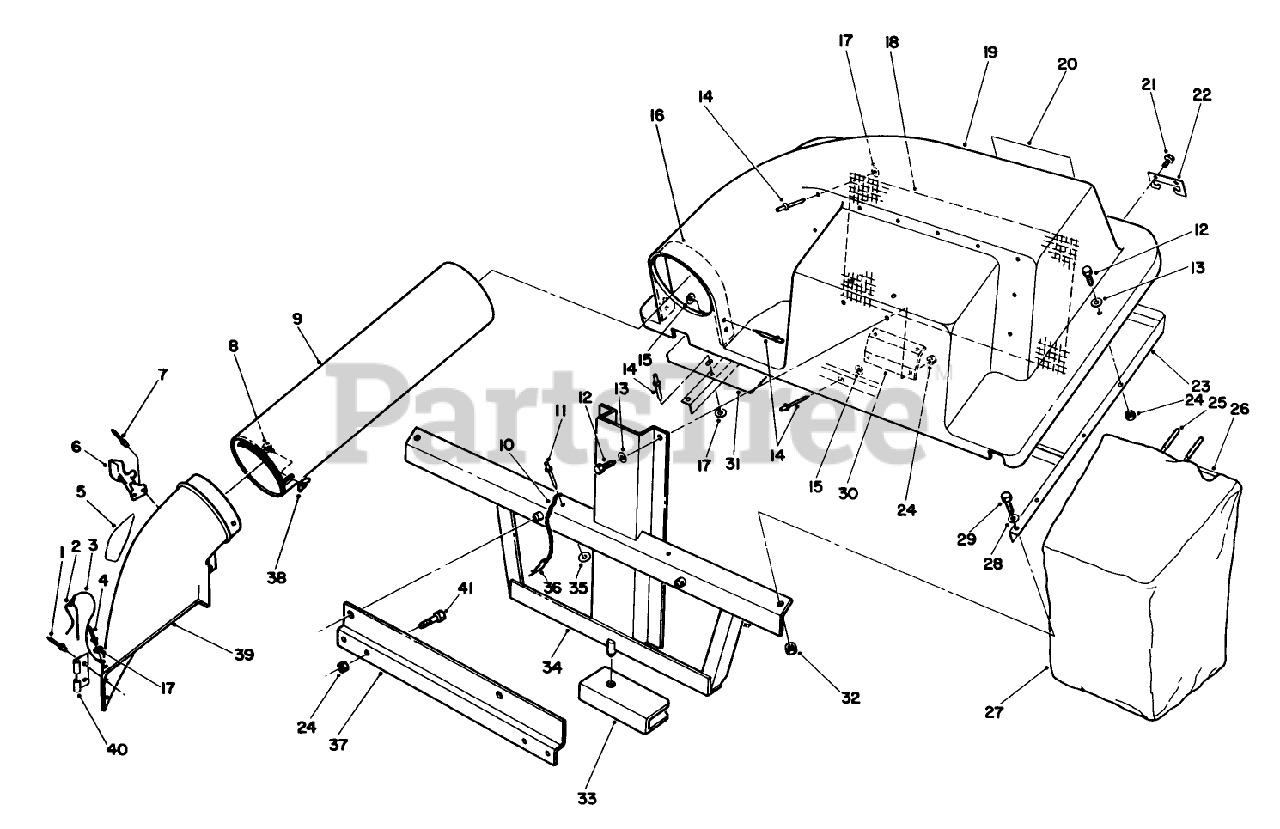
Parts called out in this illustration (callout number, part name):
1	RIVET-BLIND
2	PIN-LOCKING, CHUTE
3	LANYARD
4	RIVET-BLIND
7	RIVET-POP
8	BOLT-CARR
12	SCREW-HH
13	WASHER-PLAIN
14	RIVET-POP
15	WASHER-FLAT
17	WASHER-PLAIN
18	SCREEN
19	COVER-BAGGER, TWIN
20	DECAL-BAGGER, TWIN
21	SCREW-HWH
22	BRACKET-FRAME, BAG
24	NUT-LOCK, NI
25	GRIP-HANDLE, BAG
28	WASHER-FLAT
29	SCREW-HH
32	NUT-LOCK, NI
33	GRASS CATCHER BRKT*
35	WASHER-BACK
36	PIN-HAIR
38	NUT-WING SPECL
39	CHUTE ASM
40	BRACKET-MOUNTING, CHUTE
41	SCREW-HH
